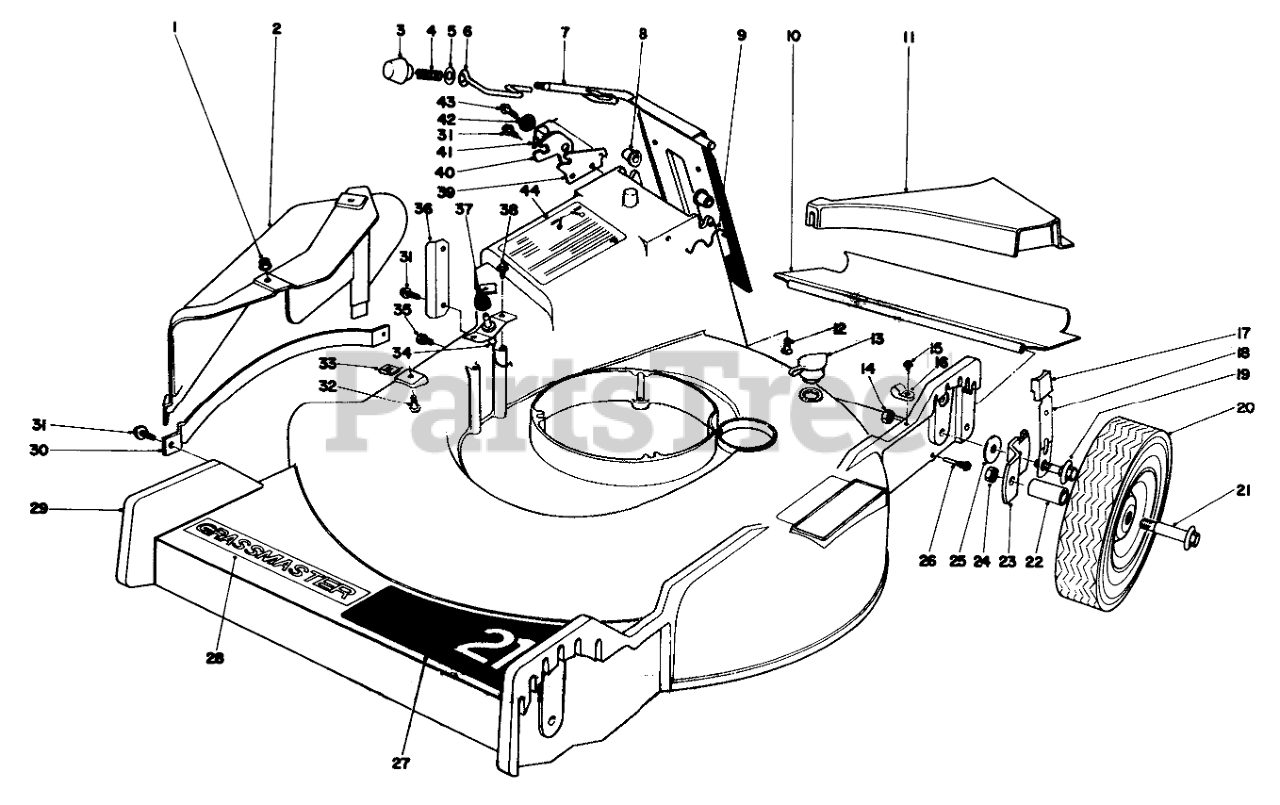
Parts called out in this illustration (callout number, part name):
1	NUT-HF
2	DEFLECTOR
4	COMPRESSION SPRING
5	WASHER
6	DOOR LATCH
7	Door Handle
8	BUSHING-NYLON
9	Door Retainer
10	REAR SAFETY SHIELD
11	REAR INSERT
12	SCREW-HH
13	WASHOUT PLUG
14	Nut
15	Screw
16	CABLE CLAMP
17	Arm Knob
18	SPRING ARM ASM
19	PIVOT SCREW
20	Wheel Assembly
22	Bushing
23	PIVOT ARM PLATED
24	Nut
25	WASHER-PIVOT
26	SAFTEY SHIELD SCREW
27	Decal
28	Decal Grassmaster
29	Housing
30	Bar Safety
31	SCREW
33	NUT-SPEED
34	Deflector Switch Assembly (Incl. Ref. #37)
35	SCREW THD 1/4 20 5/8
36	Clip Retaining
37	Boot Switch
39	DOOR LATCH PLATE
40	Latch Safety
41	Torsion Spring
42	Latch Spacer
43	Screw
44	Decal-Caution
